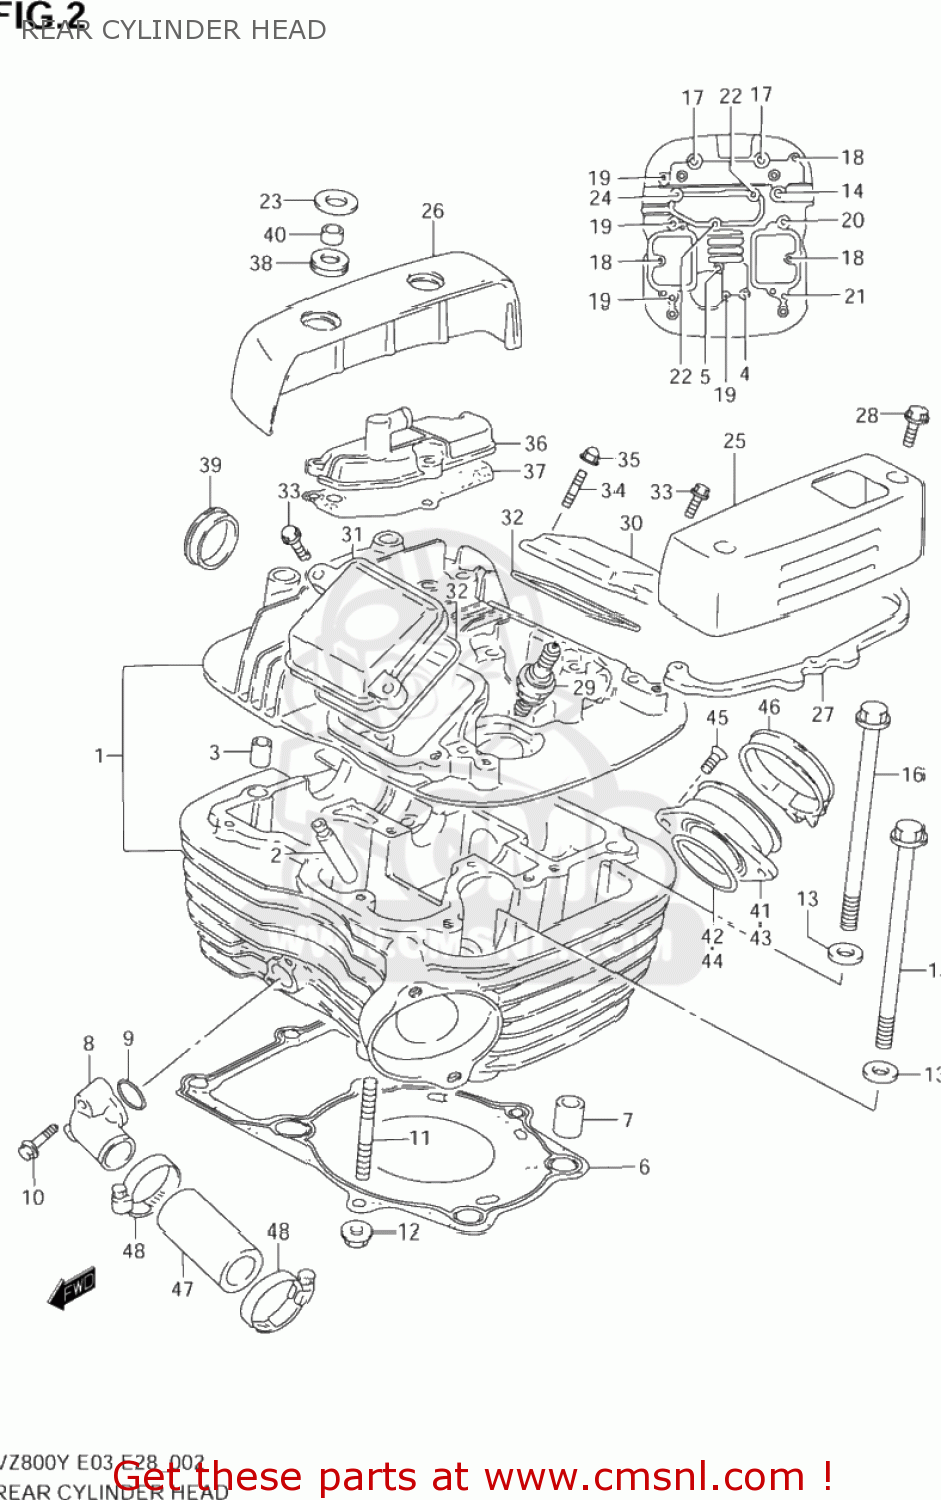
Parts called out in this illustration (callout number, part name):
1	HEAD ASSY,CYLINDER RR
2	PIN(8.4X11X14)
3	BOLT(6X50)
4	BOLT(6X55)
5	GUIDE,VALVE
6	GASKET,CYLINDER HEAD RR (NAS)
7	PIN
8	UNION,CYLINDER HEAD WATER
9	O RING(D:2.4,ID:17.8)
10	SCREW
11	BOLT,STUD
12	NUT
13	WASHER(10.5X22X2.3)
14	BOLT(8X140)
15	BOLT(10X155)
16	BOLT(10X165)
17	BOLT(8X245)
18	BOLT
19	BOLT
20	BOLT
21	BOLT
22	BOLT(6X55)
23	WASHER(8.5X24X1.6)
24	BOLT
25	CAP,CYLINDER HEAD COVER,R-L
26	CAP,CYL HEAD COVER,FL & RR
27	CUSHION,RR,L CAP
28	BOLT(6X35)
29	SPARK PLUG X22E
30	CAP,INSPECTION INTAKE
31	CAP,INSPECTION EXHAUST
32	GASKET,INSPECTION CAP (NAS)
33	BOLT
34	STUD 6X16
35	NUT
36	COVER,BREATHER
37	GASKET,BREATHER COVER (NAS)
38	CUSHION
39	PLUG(OD:30)
40	BUSH
41	PIPE,INTAKE,REAR
42	O RING(D:2.4,ID:39.7)
43	PIPE ASSY,INTAKE RR
44	O RING(D:2.4,ID:39.7)
45	SCREW
46	CLAMP
47	HOSE,CYLINDER HEAD JOINT
48	CLAMP
